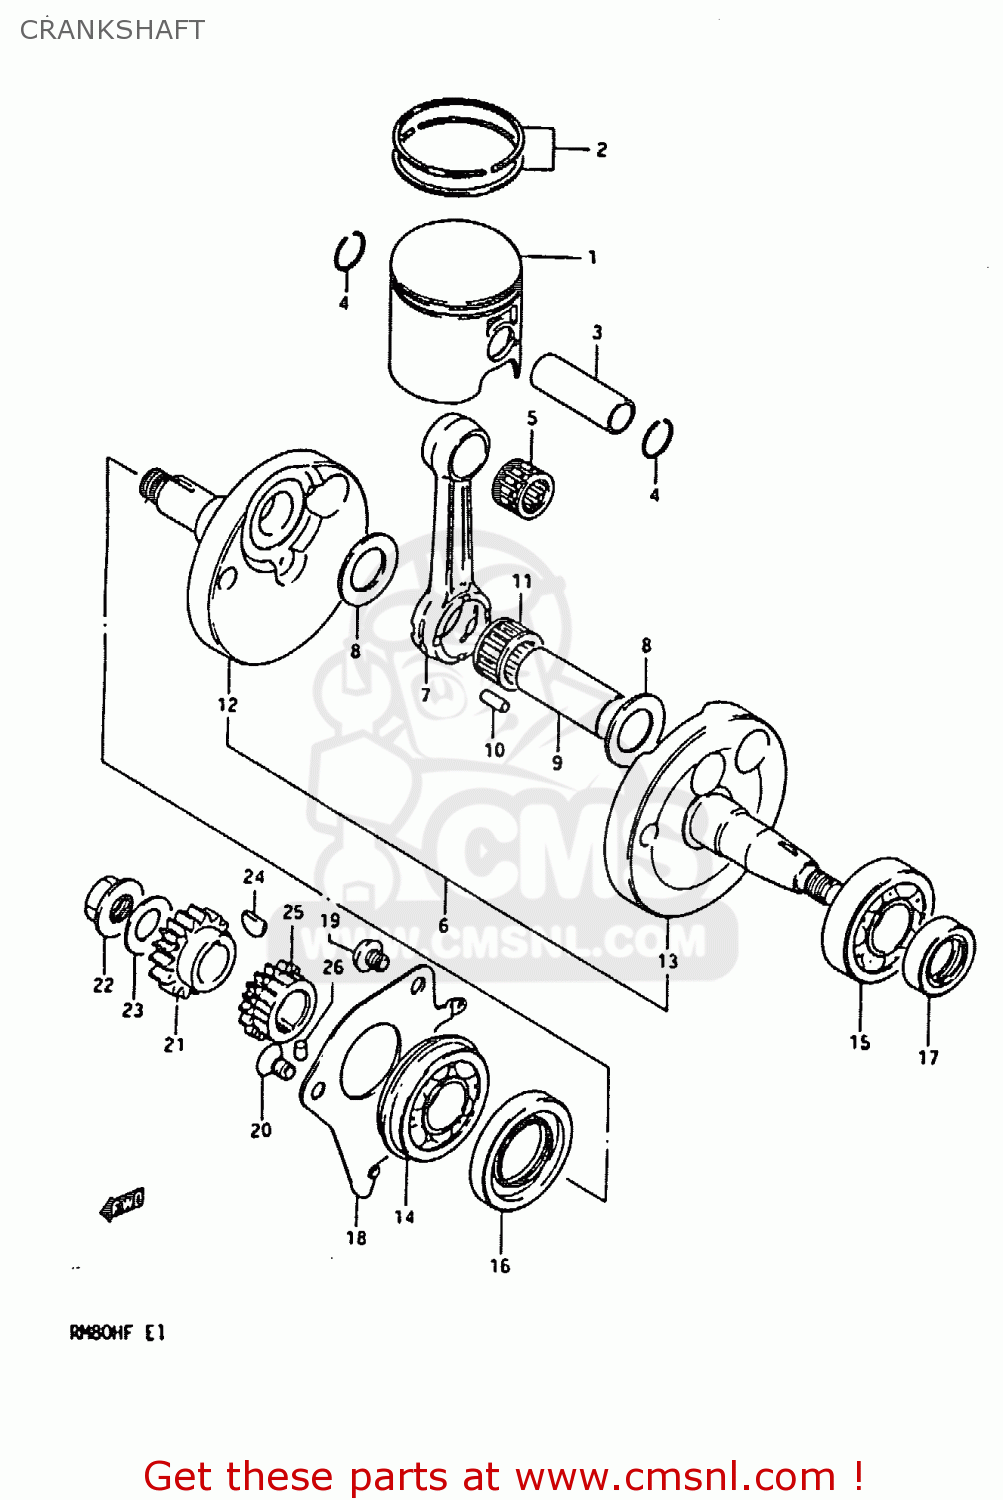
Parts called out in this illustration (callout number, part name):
1	PISTON
2	RING SET,PISTON
3	PIN,PISTON
4	RING,SNAP 14MM
5	BEARING(14X18X16)
6	CRANKSHAFT ASSEMBLY
7	ROD,CONNECTING
8	WASHER(18X32X1)
9	PIN,CRANK
10	ROLLER(3X11)
11	CAGE
12	CRANKSHAFT
13	CRANKSHAFT,LEFT
14	BEARING(20X47X14)
15	BEARING
16	SEAL,OIL(26X47X7.3)
17	SEAL,OIL(18X30X8)
18	PLATE,CRANKSHAFT BEARING
19	SCREW 6X12
20	SCREW
21	GEAR,PRIMARY DRIVE
22	NUT
23	WASHER
24	KEY
25	GEAR,WATER PUMP DRIVE
26	PIN 3X5
